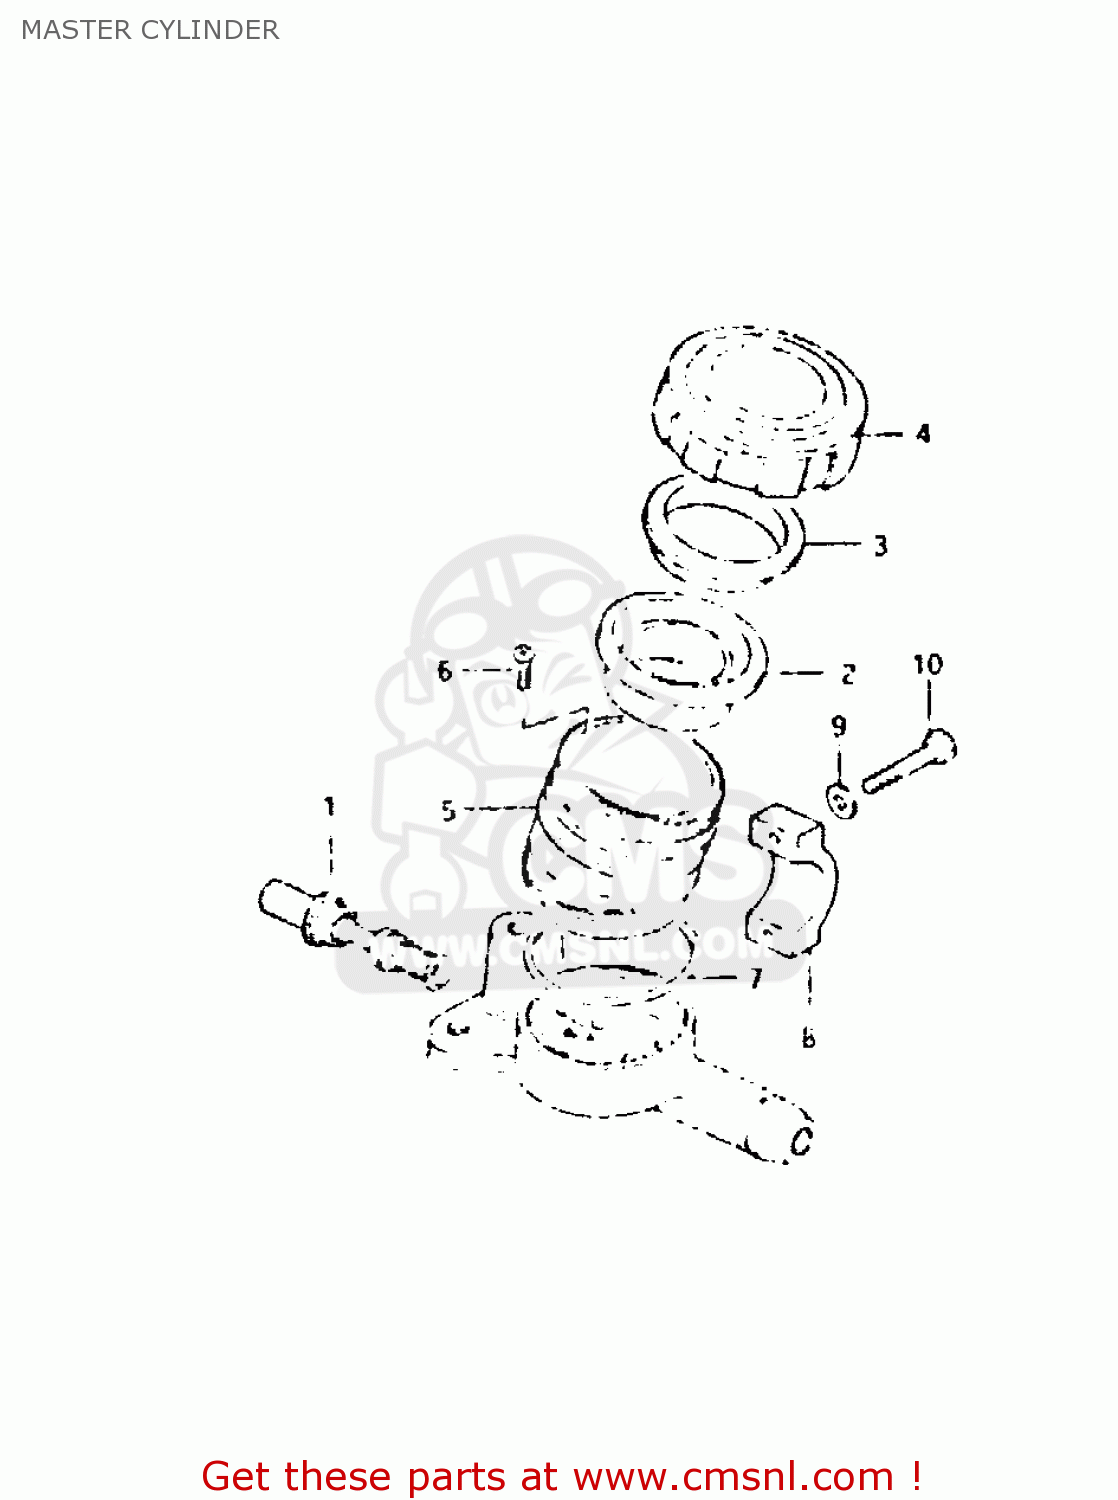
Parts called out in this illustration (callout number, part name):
1	PISTON & CUP SET
2	DIAPHRAGM
3	PLATE,DIAPHRAGM
4	CAP
5	RESERVOIR
6	SCREW,MASTER CYLINDER
7	O RING
8	HOLDER,MASTER CYLINDER
9	WASHER
10	BOLT
